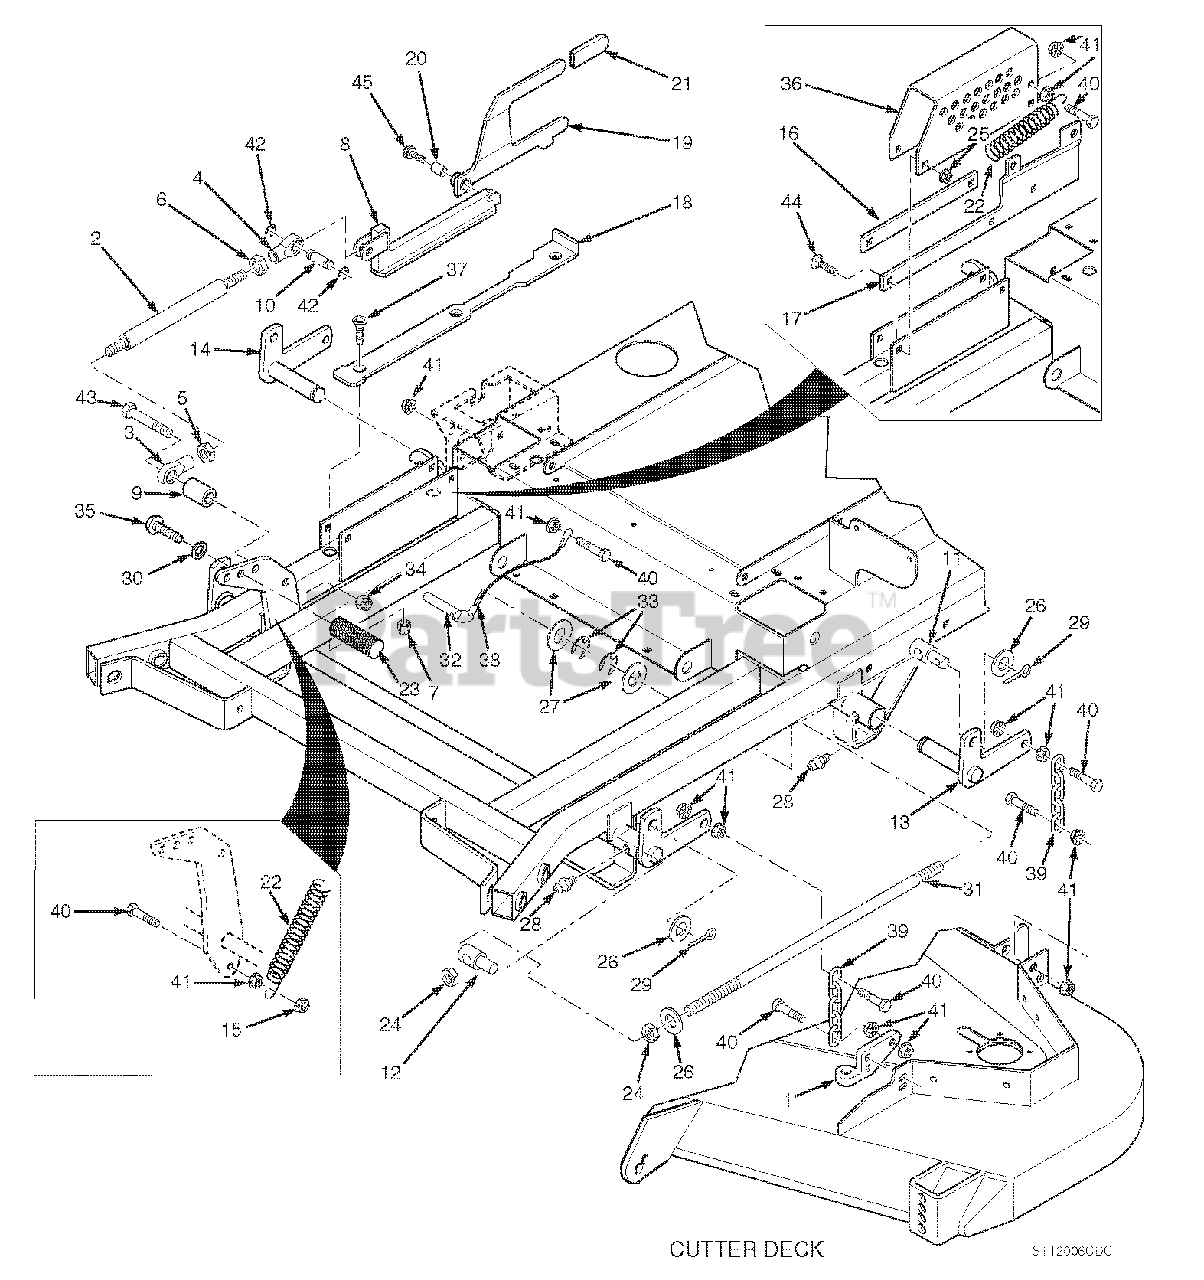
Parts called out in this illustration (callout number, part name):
1	Lever Assembly, Deck Level
2	Link, Deck Lift
3	Rod End, Female - 1/2-20 RH
4	Rod End, Female - 1/2-20 LH
5	Nut, Jam 1/2-20 RH
6	Nut, Jam 1/2-20 LH
7	Nut, 3/8-16 Elastic Stop
8	Slide Weldment, Height Adjustment
9	Spacer, Decklift Pedal
10	Pin, Decklift
11	Swivel Joint, LH
12	Swivel Joint, RH
13	Bellcrank Weldment, LH Rear
14	Bellcrank Weldment, RH Rear
15	Locknut, 3/8-16 Center Lock
16	Guide, Short
17	Guide, Long
18	Lockplate, Decklift
19	Deck Latch
20	Bushing, .502" I.D.
21	Grip, Deck Latch
22	Spring, Helper
23	Foot Pedal, Height Adjustment
24	Nut, Hex 5/8-11
25	Nut, Hex Serr. Flng. 5/16-18
26	Flatwasher, 5/8" (.656 x 1.312 x .095")
27	Flatwasher, 1" (1.062 x 1.50 x .048")
28	Grease Fitting
29	Cotter Pin, 3/16 x 1"
30	Lockwasher, 5/8"
31	Stud, 5/8-11 x 22.0"
32	Ring Pin, 1/2 x 3.06"
33	Ring, Retaining 1" External "E"
34	Nut, Hex Elastic Stop 1/2-13
35	Capscrew, 5/8-11 x 1-1/2"
36	Bracket, Cutting Height Adjustment
37	Screw, Cap 5/16-18 x 3" FHHS
38	Lanyard, Deck Height Pin
39	Chain
40	Bolt, Hex Hd. 3/8-16 x 1-1/2"
41	Nut, Hex Serr. Flng. 3/8-16
42	Ring, Retaining 1/2" External "E"
43	Bolt, Hex Hd. 1/2-13 x 3"
44	Bolt, Carriage 5/16-18 x 1"
45	Bolt, Shoulder 1/2 x 3/4"
